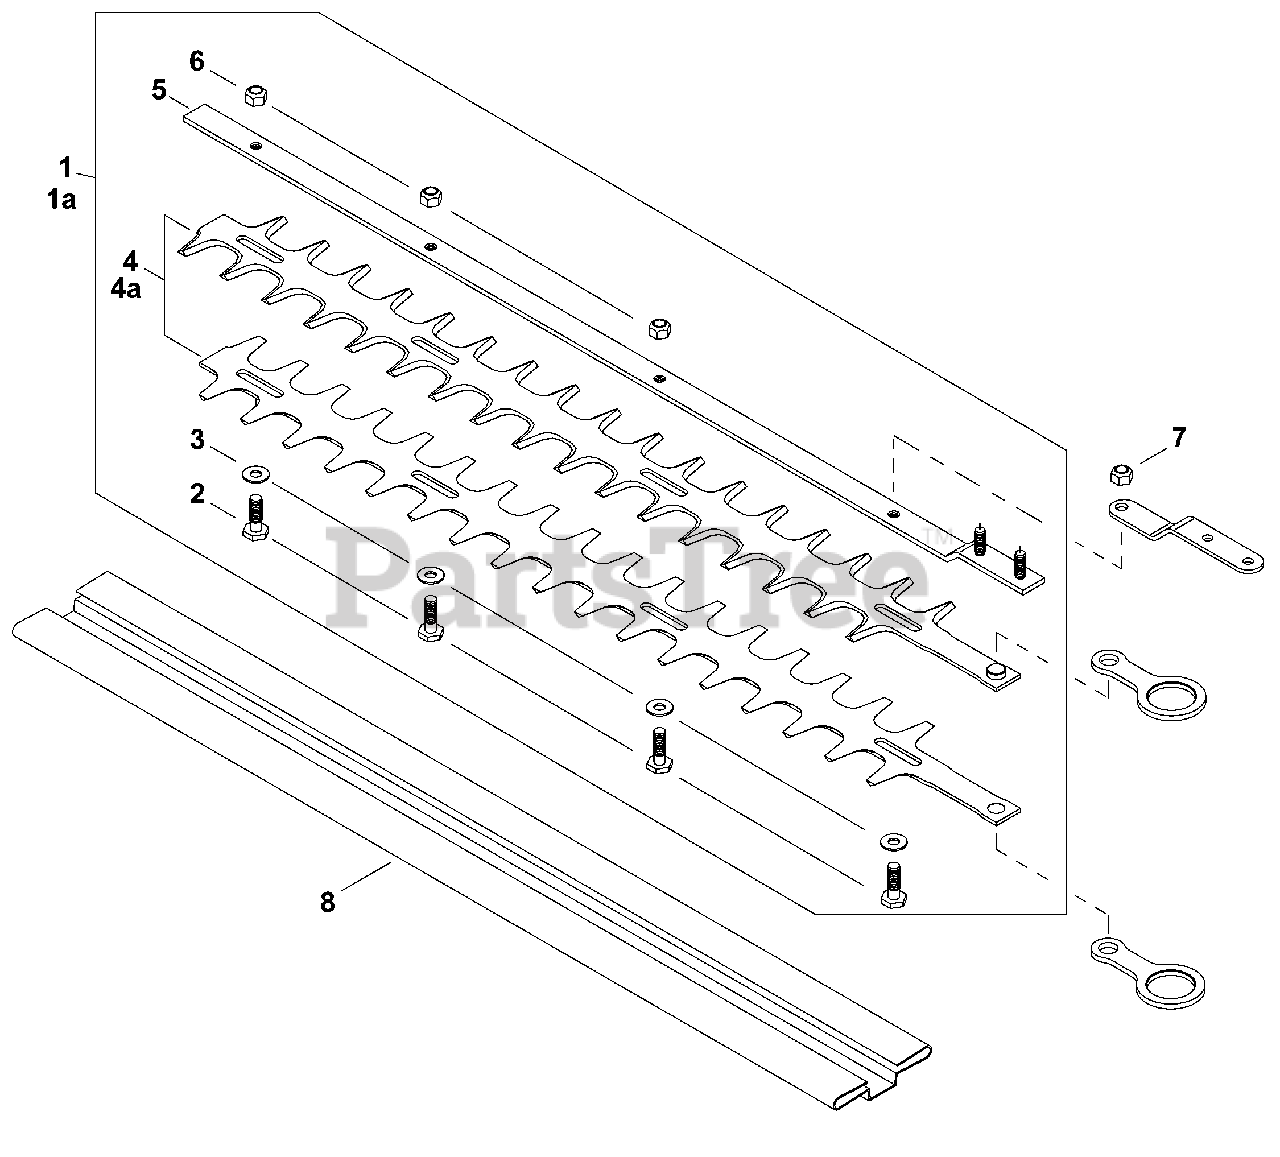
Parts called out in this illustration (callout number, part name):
1	CUTTER ASSY, 22" CHROME
2	BOLT M6×20
3	WASHER M6
4	CUTTER, CHROME 22"
5	GUIDE BAR 22"
6	NUT, LOCK M6
7	NUT, LOCK M6
8	SCABBARD
